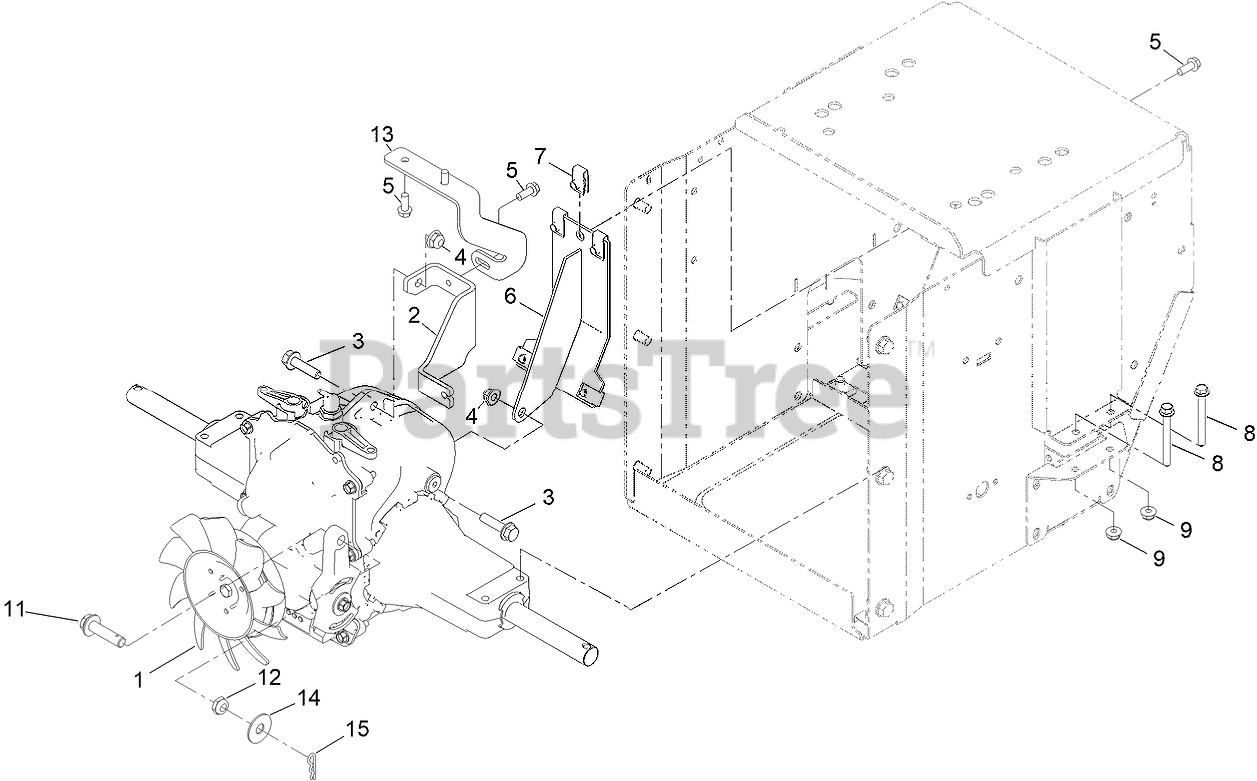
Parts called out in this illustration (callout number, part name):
1	HYDRO - SST
2	BRACKET-HYDRO, CABLE
3	SCREW-HHF
4	NUT-HF
5	SCREW-HWH
6	BRACKET-HYDRO, REAR
8	SCREW-HHF
9	NUT-HF
11	SCREW-HHF SPCL
13	BRACKET-HYDRO, UPPER
14	WASHER-FLAT
